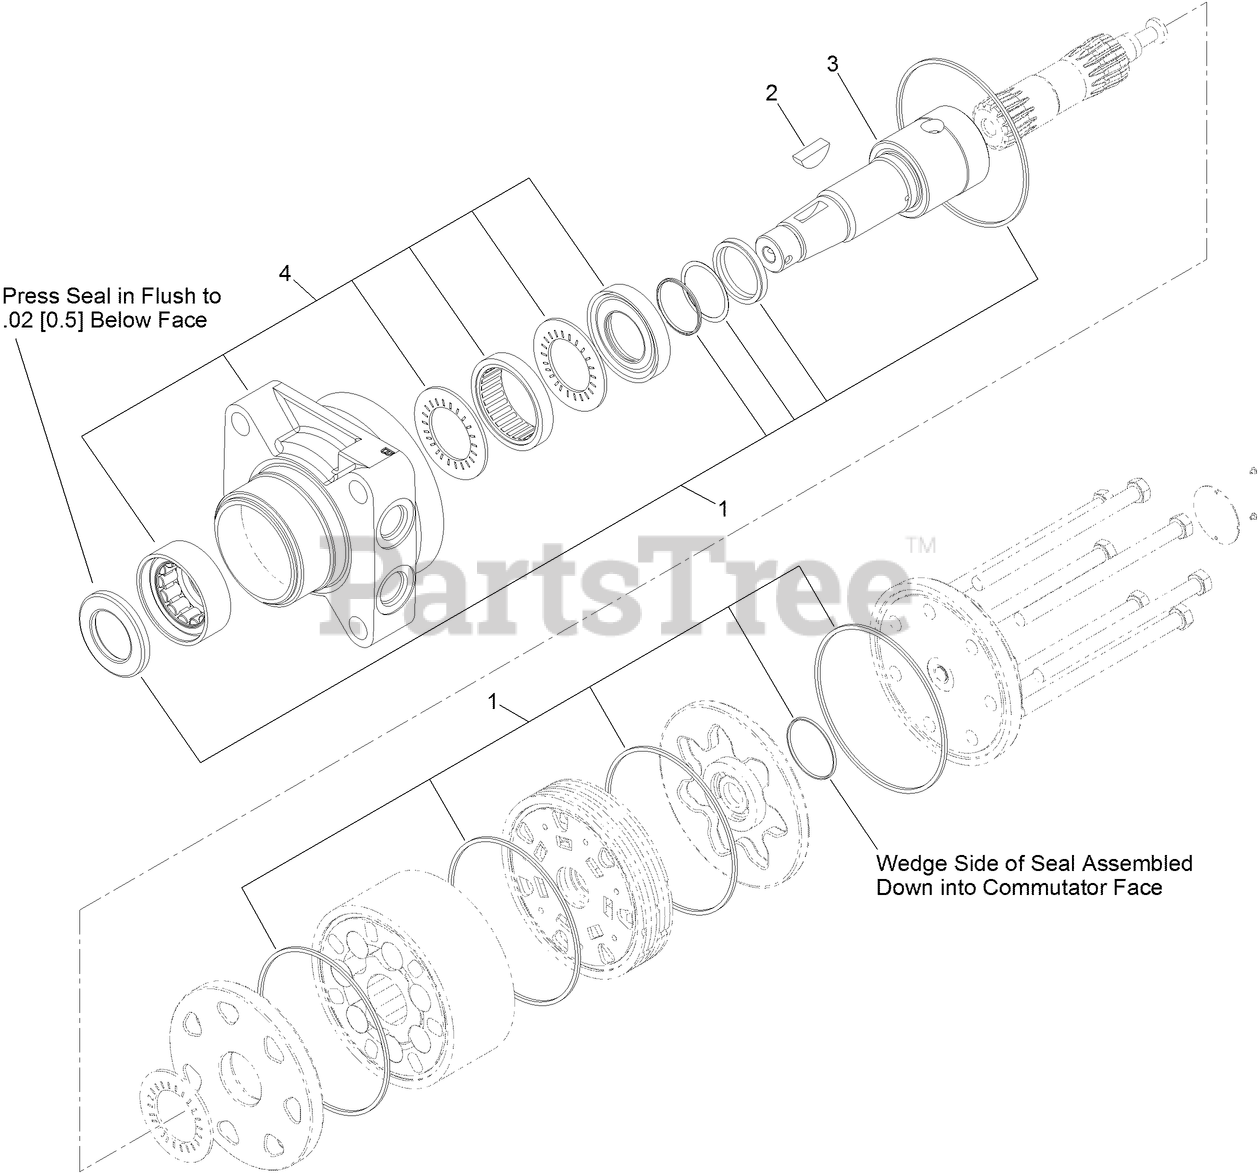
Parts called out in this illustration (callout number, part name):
1	SEAL KIT
2	KEY-WOODRUFF
3	SHAFT-COUPLING
4	MOTOR HOUSING ASM
